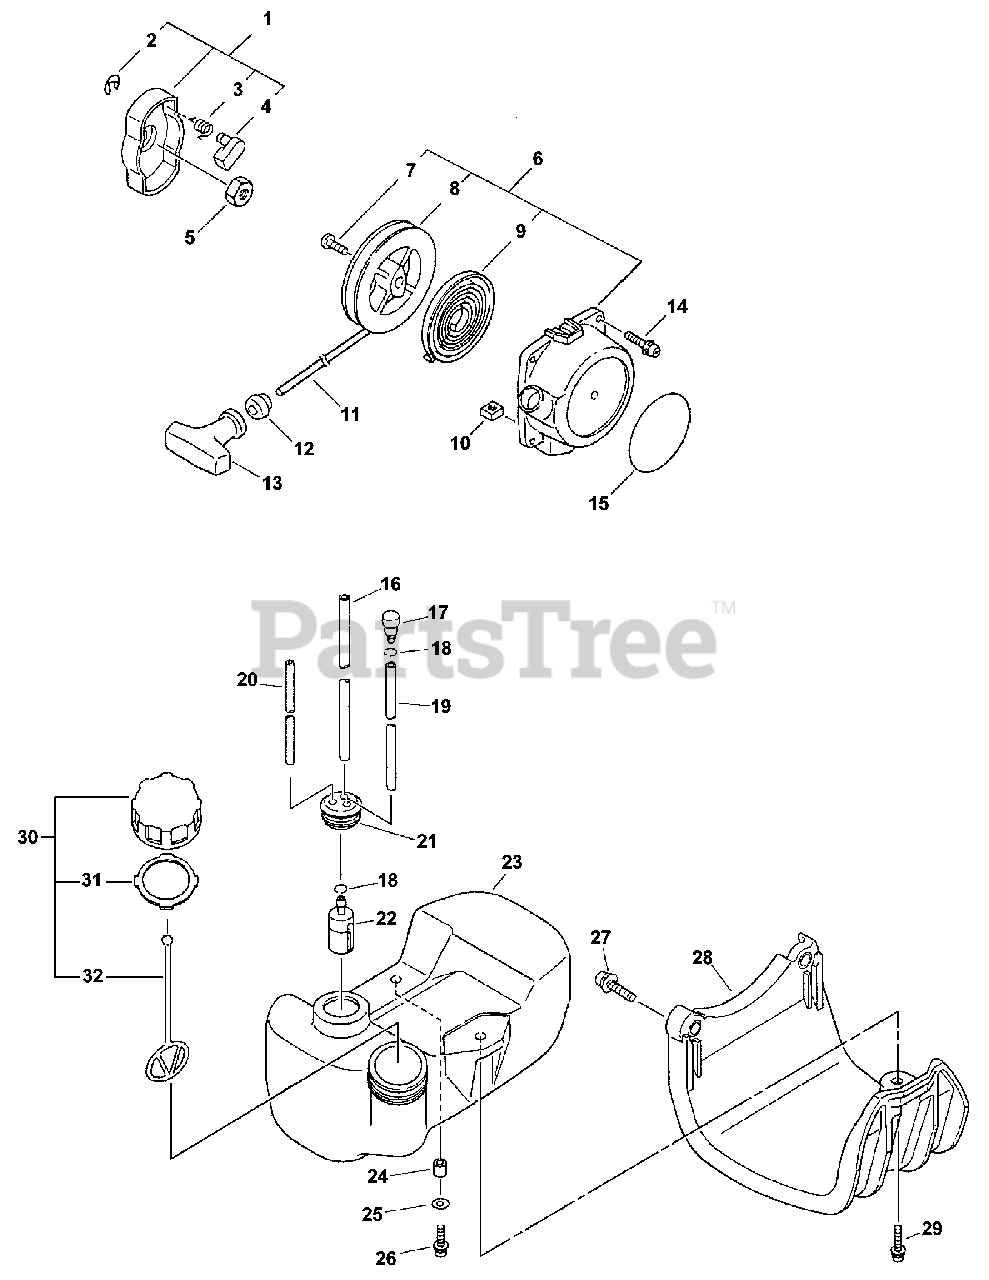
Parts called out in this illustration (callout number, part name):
1	PAWL ASSY, STARTER
2	E-RING 4
3	SPRING, RETURN
4	PAWL, STARTER
5	NUT 8×1.25
6	STARTER ASSY, RECOIL
7	SCREW
8	REEL, ROPE
9	SPRING, RECOIL
10	NUT M5
11	ROPE, STARTER 3.5×850
12	GUIDE, ROPE
13	GRIP, STARTER
14	BOLT 4×12
15	LABEL, ECHO
16	PIPE, FUEL 3×6×165
17	VENT ASSY
18	CLIP Ø6.5 MM
19	PIPE 3×6×115 BLACK
20	PIPE, FUEL 3×6×80 CLEAR
21	GROMMET, FUEL
22	FILTER, FUEL
23	TANK, FUEL
24	SPACER 6.2×7.8×6
25	WASHER 5.5×12×0.8
26	BOLT 5×16
27	BOLT 5×22
28	GUARD, FUEL TANK
29	SCREW 5×20
30	CAP ASSY, FUEL
31	GASKET, FUEL CAP
32	CONNECTOR, CAP L= 100 MM
